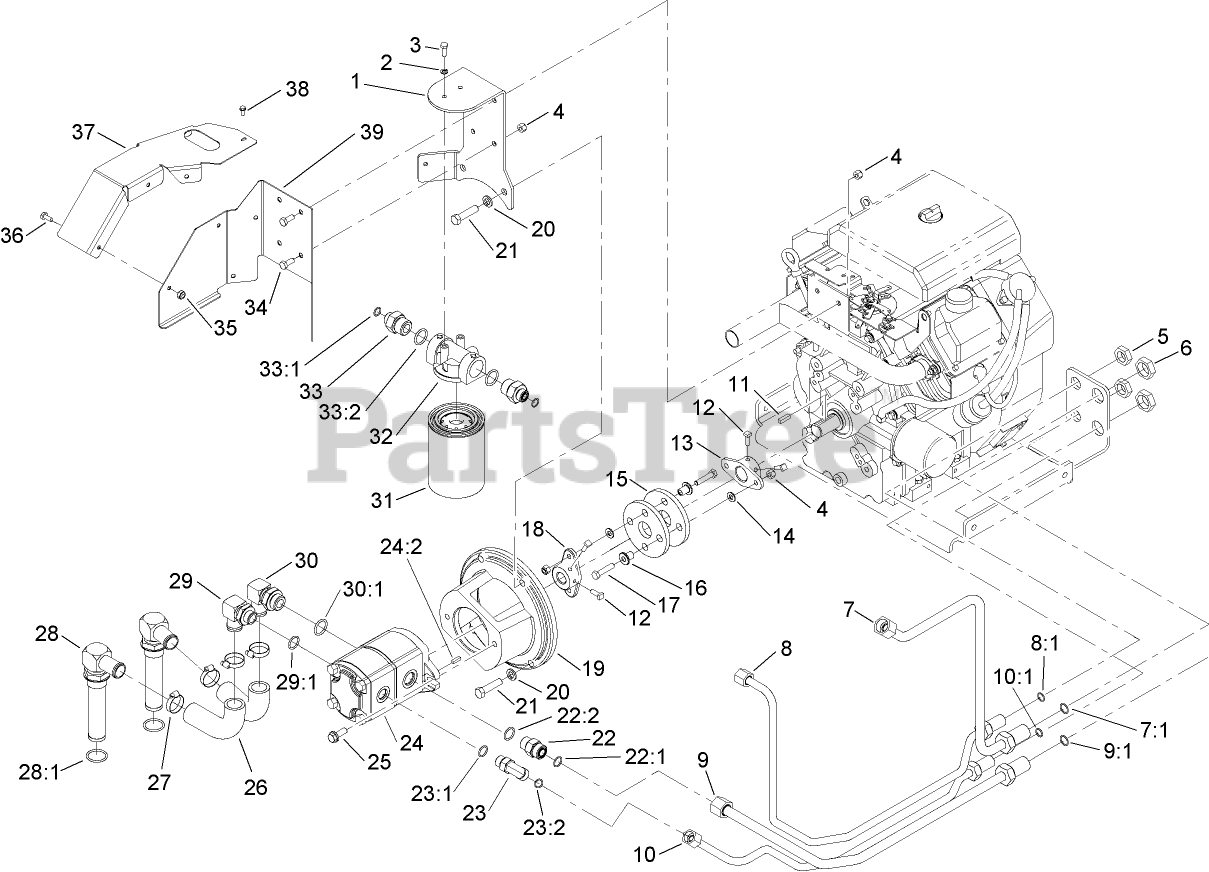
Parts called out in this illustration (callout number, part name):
1	BRACKET-SUPPORT, OIL FILTER
2	WASHER-LOCK
3	SCREW-HH
4	NUT-LOCK, NI
5	NUT-BULKHEAD
6	NUT-LOCK, BULKHEAD
7	HYD TUBE ASM
7:1	O-RING
8	HYD TUBE ASM
8:1	O-RING
9	HYD TUBE ASM
9:1	O-RING
10	HYD TUBE ASM
10:1	O-RING
11	KEY-SQUARE
12	SCREW-SQH
13	HUB-ENGINE
14	WASHER-PLAIN
15	COUPLING-RUBBER
16	SPACER
17	SCREW-HH
18	HUB-PUMP
19	MOUNT-PUMP
20	WASHER-LOCK
21	SCREW-HH
22	FITTING-STRAIGHT
22:1	O-RING
22:2	O-RING
23	FITTING-ELBOW-90 DEG
23:1	O-RING
23:2	O-RING
24	PUMP-GEAR, HYD
24:2	KEY-SQUARE
25	SCREW-HHF
26	HOSE-SUCTION, FORMED
27	CLAMP-HOSE
28	STRAINER FITTING ASM
28:1	O-RING
29	STEM-HOSE, 90 DEG
29:1	O-RING
30	FITTING-HYD, 90 DEG
30:1	O-RING
31	FILTER-OIL
32	HEAD-FILTER
33	FITTING-STR
33:1	O-RING
33:2	O-RING
34	SCREW-HH
35	NUT-LOCK, NI
36	SCREW-HH
37	SHIELD-HEAT
38	SCREW-HWH
39	SHIELD-HEAT, FILTER
